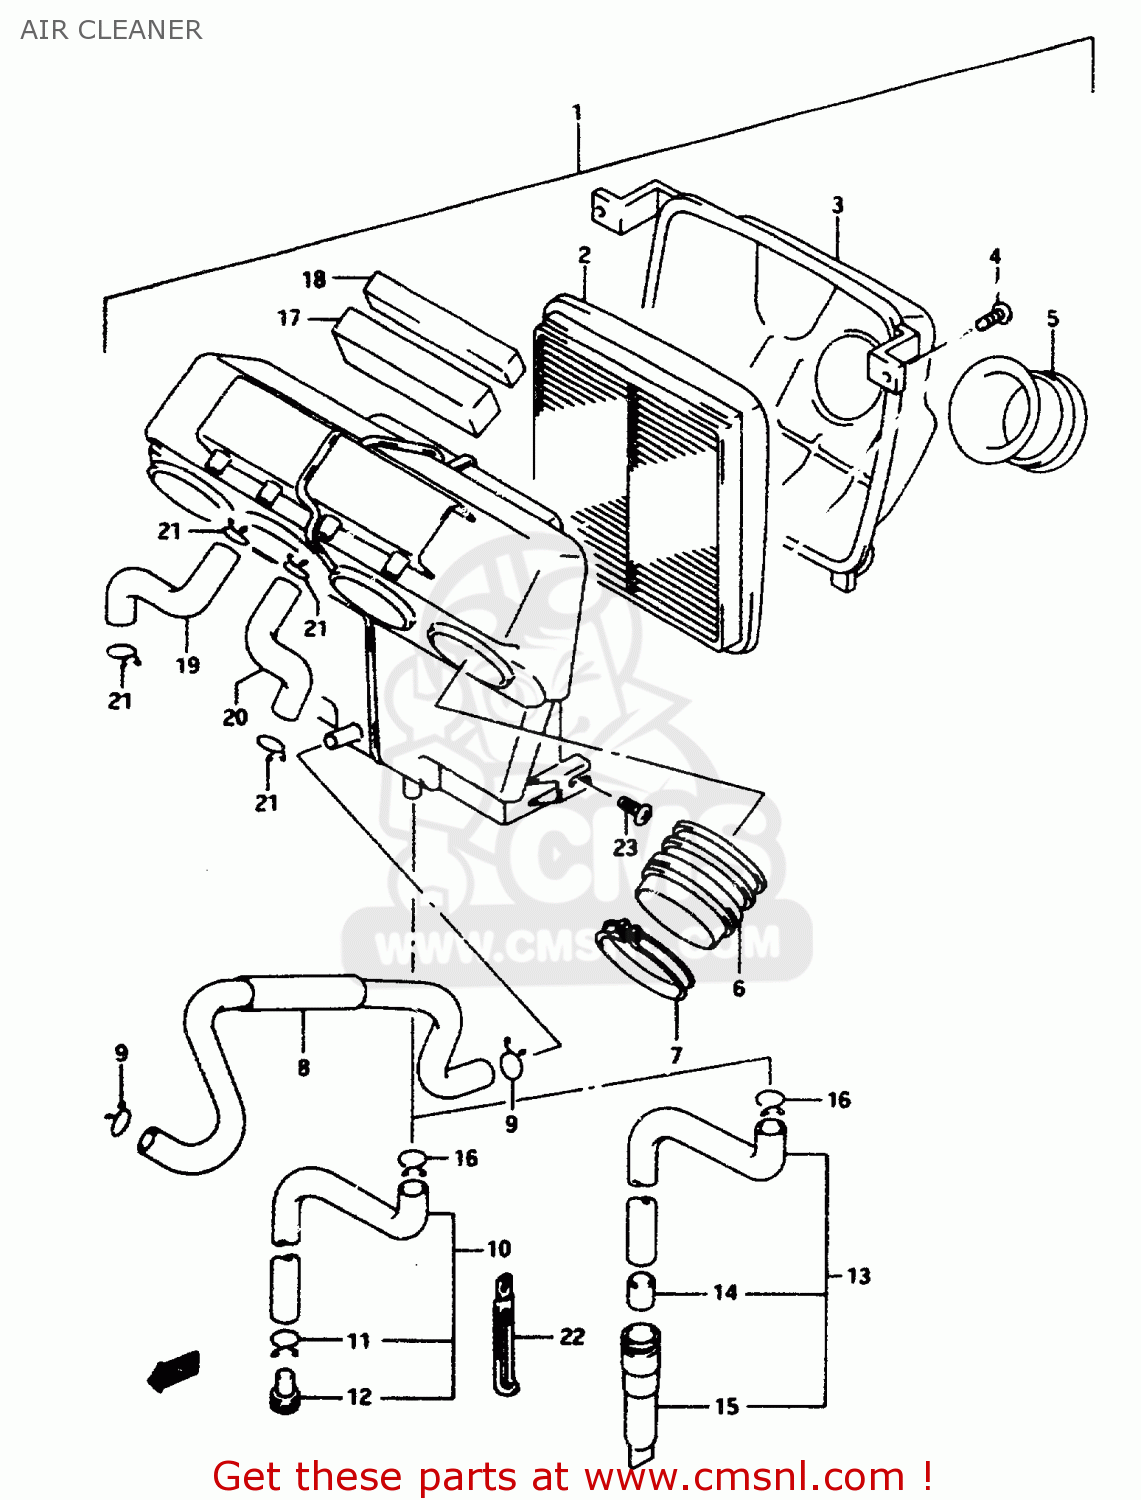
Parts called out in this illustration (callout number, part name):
1	CLEANER ASSY,AIR
2	FILTER,AIR
3	CAP,AIR CLEANER
4	SCREW
5	TUBE,INLET
6	TUBE,OUTLET
7	CLAMP
8	TUBE,BREATHER
9	CLIP
10	DRAIN TUBE
11	CLIP
12	STOPPER,DRAIN
13	TUBE,DRAIN
14	FILTER,DRAIN
15	CAP,DRAIN
16	CLIP
17	FILTER,CARB AIR
18	FILTER,AIR NO.2
19	TUBE,CARBURETOR AIR,R
20	TUBE,CARBURETOR AIR,LEFT
21	CLIP
22	CLAMP
23	SCREW
